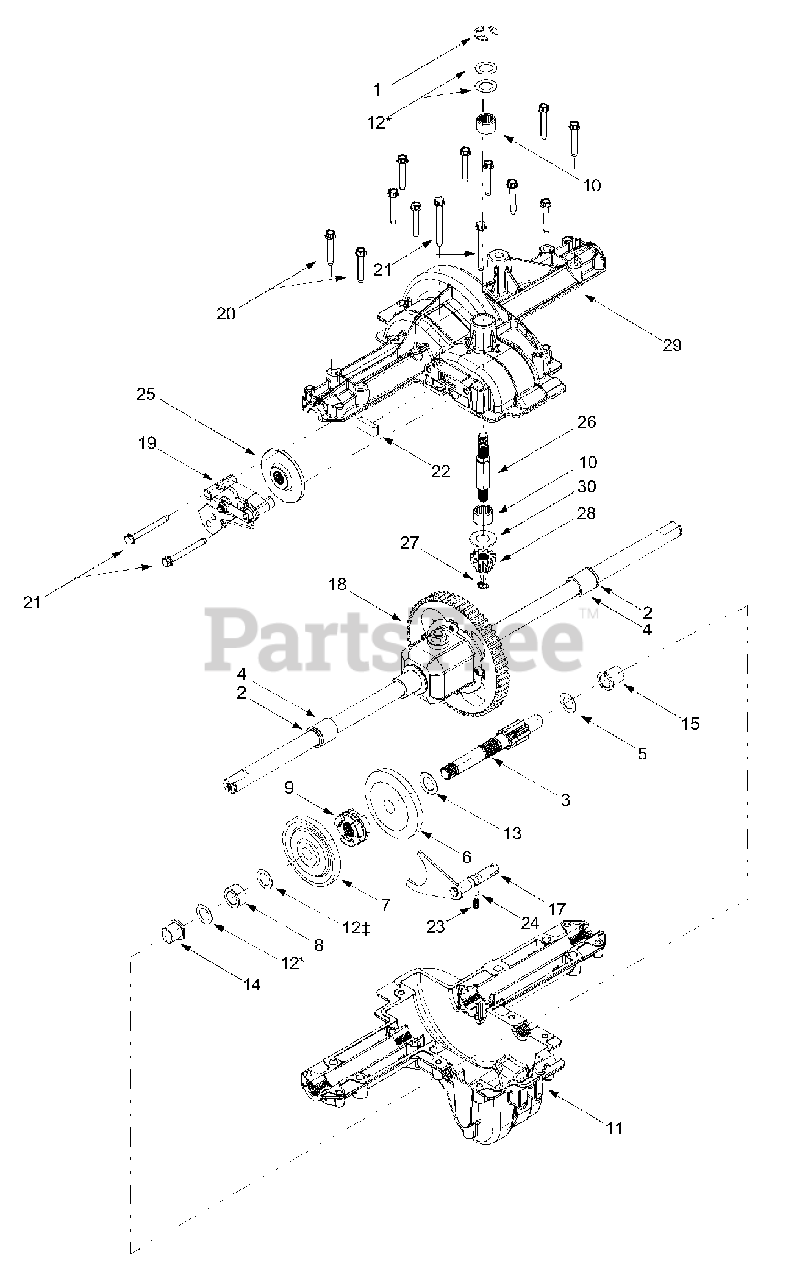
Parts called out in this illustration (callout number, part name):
1	E-ring, .75
2	Seal, .75 x 1.0 x .125
3	Drive Shaft
4	Sleeve Bearing, .75 x .1.0 x 1.0
5	Thrust Washer, 1.0 x .632 x .0
6	42-tooth Bevel Gear
7	42-tooth Bevel Gear
8	Spacer, .633 x 1.0 x .513
9	Clutch Collar
10	Needle Bearing, .625 x .875
11	Lower Housing
12	Flat Washer, 5/8 x 1.0 x .030
13	Flat Washer, .70 x 1.125 x .031
14	Flange Bearing, 5/8 x 3/4 x 3/4
15	Flange Bearing, 5/8 x 3/4 x 15/16
17	Detent Shaft Assembly
18	Differential Assembly
19	Brake Assembly
20	Self-tapping Screw, 1/4-20 x 1.625
21	Self-tapping Screw, 1/4-20 x 2.375
22	Brake Pad
23	Compression Spring
24	Detent Ball
25	Brake Disc
26	Input Shaft
27	Retaining Ring, .437
28	14-tooth Bevel Pinion
29	Upper Housing
30	Thrust Washer, .635 x 1.25 x .042
